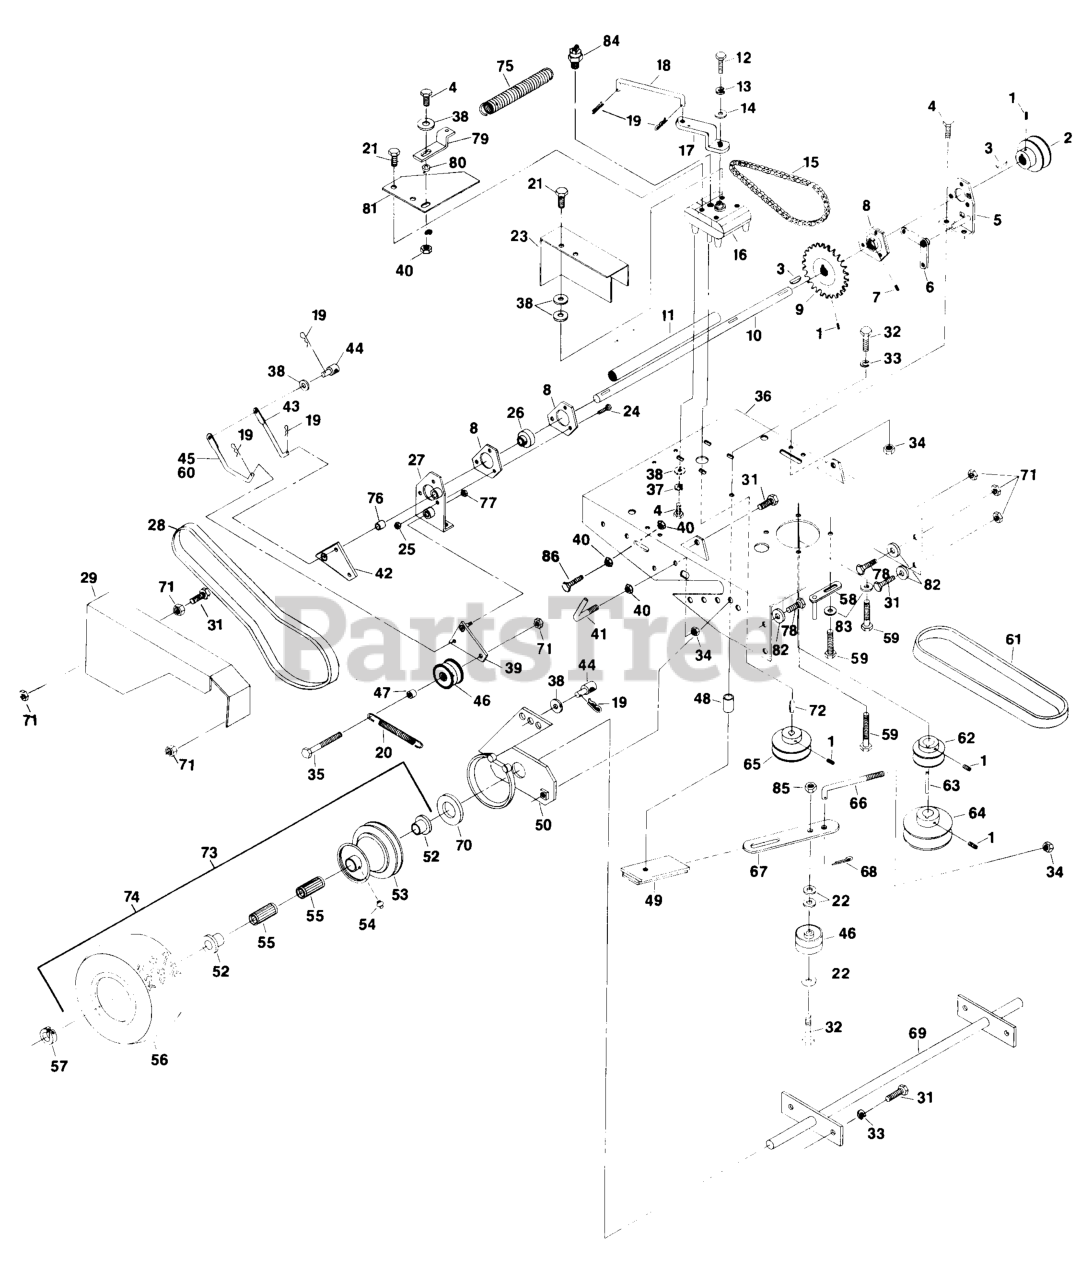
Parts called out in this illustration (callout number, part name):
1	SCREW-SET
6	BELLCRANK
10	JACKSHAFT
13	WASHER-LOCK
15	CHAIN,DRIVE
17	LEVER,TRANSMISSION
19	PIN-COTTER
20	SPRING-EXTENSION
28	BELT,COG
30	FENDER WLDMT,5SP LH UU
37	WASHER-LOCK
39	ARM - IDLER
42	ARM - IDLER
44	SWIVEL,SHORT ADJUSTING
45	LINKAGE,LOWER CALIPER RH
46	PULLEY,IDLER
55	BEARING,ROLLER WHEEL 32
55	BEARING,ROLLER
57	COLLAR,LOCKING 7/8
58	GUIDE - BELT, 32
59	WASHER-LOCK
59	SCRW,TPTTE HH
61	BELT,TRANSMISSION
63	KEY,MACH 1/4X1/4X2-5/8
64	PULLEY,CAST IRON
66	TIGHTENING ARM
69	WLD,AXLE 32
77	NUTTORQUE ZKPLT
83	WASHER-SPRING
84	SWITCH-START, NEUTRAL
